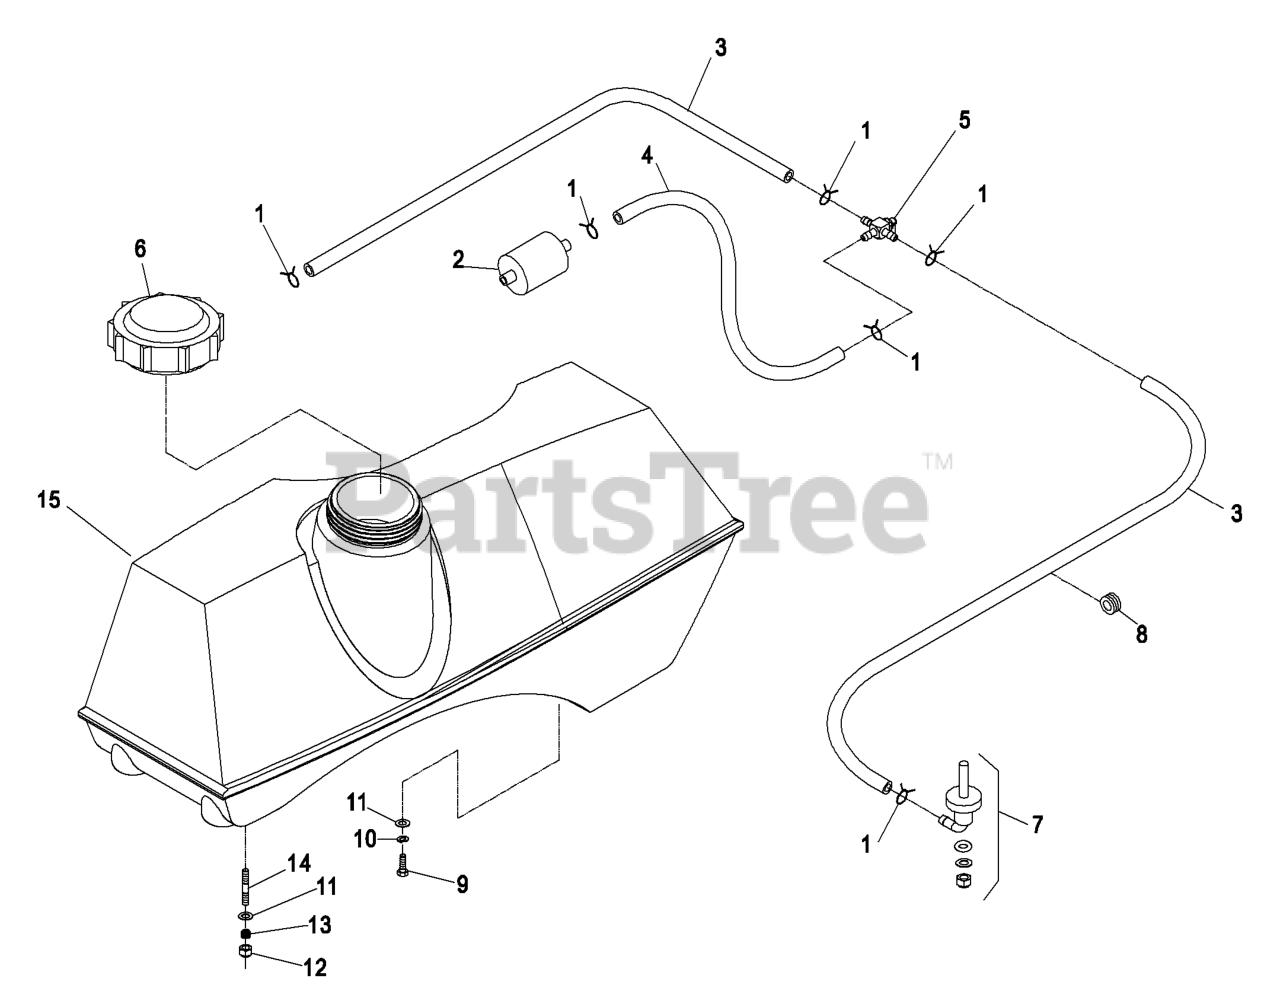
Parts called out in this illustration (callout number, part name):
2	Kohler Part No. 2405002 Fuel Filter
5	VALVE-FUEL
7	FITTING-FUEL, BULKHEAD
8	GROMMET
9	SCREW-HH
10	WASHER-LOCK
11	WASHER-PLAIN
12	NUT-LOCK, NI
13	SPRING-TANK, FUEL
14	STUD
